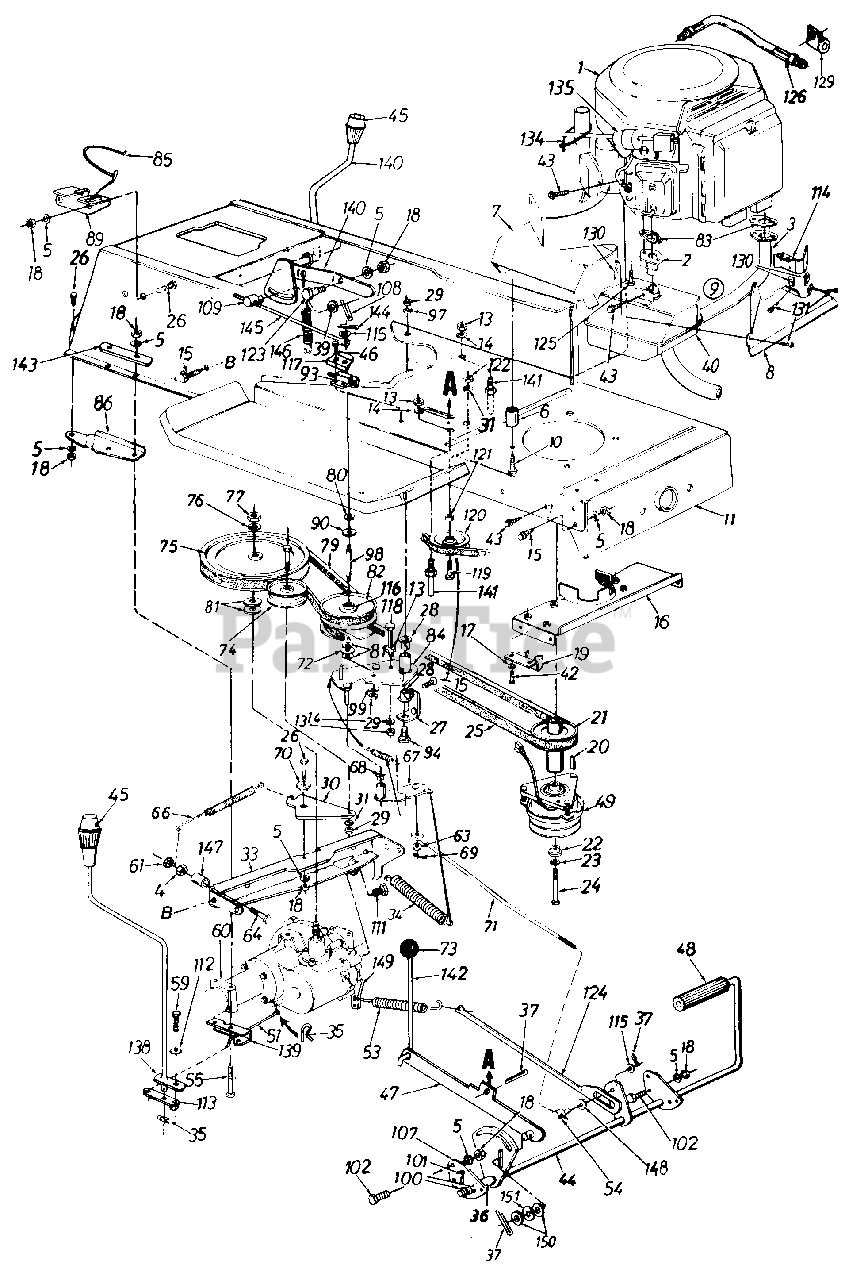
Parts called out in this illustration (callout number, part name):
1	Engine
2	Inlet Tube Ass'y.
3	Formed Tube Ass'y.
4	Hex Nut 5/16-24 Thd.
5	L-Wash. 5/16" I.D.
6	Spacer 1.25" Lg.
7	Muffler Heat Shield
8	Front Heat Shield
9	Muffler Ass'y. Comp.
10	Hex L.Wash. Tap Scr.5/16-18 x .62" Lg.
11	Lower Frame Ass'y.
13	Hex Nut 1/4"-20 Thd.*
14	L-Wash. 1/4" I.D.*
15	Hwx Wash. TT-Tap Scr. 5/16-18 x .62" Lg.
16	Belt Guard Brkt Ass'y.
17	Bell-Wash .345" I.D. x .88"
18	Hex Nut 5/16-18 Thd.
21	Engine Pulley
22	Shld. Spacer .445"I.D.
23	L-Wash.7/16" I.D.*
24	Hex Bolt 7/16-20 x 5.0" Lg.
25	Variable Speed Belt
26	Hex Bolt 5/16-18 x .75" Lg.
27	Bearing Shaft Bracket
28	Flanged Nyliner Brg. 5/8"I.D. x .88" Lg.
29	Hex Nut 3/8-24 thd.
30	Idler Bracket
31	L-Wash. 3/8" I.D.*
33	Transaxle Support Brkt
34	Ext spring .94" O.D. x 7.58"
35	Inter Cotter Pin
36	Spacer .63" I.D.
37	Cotter Pin 1/8" Dia x 1.0" Lg.
39	Fl-Wash. .51" I.D. x .75"
40	Exhaust Muffler Sub Ass'y.
42	Hex Bolt 5/16-18 x .75" Lg. (Grade5)
43	Hex Wash. Hd S-Tap Scr.1/4-20 x .50" Lg.
44	Clutch/Brake Pedal Ass'y.
45	Shift Knob
46	Hex Wash. Hd. B-Tap Scr. #10 x .5" Lg.
47	Parking Brake Lockout Brkt. Ass'y.
48	Foot Pad
49	Electric Clutch
51	Shift Lever Rod
53	Ext spring 3.6"
54	Ferrule
55	Hex Bolt 5/16-18 x 3.25"*
59	Hex Bolt 1/4-28 x .62" Lg.
60	Transaxle Complete
61	Hex L-Nut 1/4-20 Thd.
63	Fl-Wash. .34" I.D. x .68" O.D.
64	Hex Wash. TT-Tap Scr. 1/4-20 x 1 .75"
66	Ext. Spring .5" O.D. x 4.35"
68	Flanged Bearing
69	Cotter Pin 3/32" Dia.
70	Shoulder Spacer .27" Lg.
71	Speed Control Link
72	Truss Bearing .56 Dia. x 1 .25"
73	Ball Knob
74	Fl-Idler Pulley 3.25" x .75"
75	"V"-Pulley
76	Bell-Wash. .567" I.D. x 1.125"
77	Hex Jam Nut 9/16-18 Thd.
79	Variable Speed Belt
80	Snap Ring .56" Dia.
81	Fl-Wash. .56" I.D. x 1.0" O.D.
82	Variable Speed Pulley Ass'y. 5" O.D.
83	Gasket
90	Teflon Washer .565" I.D.
93	Safety Switch (Clutch)
94	Shld. Bolt 3/8-24 x 3.12" Lg.
97	Bell-Wash. .38" I.D. x .88"
98	Shaft
99	Bell-Wash. .39" I.D. x 1.12"
100	Fl-Wash. .64" I.D. x .94"
101	Cotter Pin 3/32" Dia. x 1.0"
102	Hex Wash. Hd. Scr. 5/16-18 x.62" Lg.
109	Ferrule
111	Hex Wash. Tap Scr. 5/16-18 x 1.25" Lg.
112	Bell-Wash. .265" I.D. x .75"
113	Shift Lever Link Ass'y.
114	Front Heat Shield Ext.
115	Fl-Wash. .385" I.D. x .62"
116	Needle Brgs.
117	Switch Plate
118	Hex Bolt 1/4-20 x 3.25" Lg.
119	Hex Bolt 3/8-16 x 1.25" Lg.
120	Fl-Idler w/Flanges 2.75" O.D.
121	Fl-Wash. .39" I.D. x 1.12" O.D.
122	Hex Nut 3/8-16 Thd.
123	Shld. Bolt .437" Dia. x .162"
124	Brake Rod Ass'y.
125	Hex Bolt w/Washer
126	Oil Drain
129	Clamp
130	Speed Nut #10-24 Thd.
131	Hex AB-Tap Scr. #10 x .5" Lg.
134	Cable Tie
135	Hose Clamp
138	Shift Lever Ass'y.
139	Shift Lever Support Brkt.
140	Speed Selector Lever Ass'y.
141	Belt Guard Pin
142	Brake Lockout Rod
144	Cotter Pin 1/8" x 3/4" Lg.
145	Speed Selector Rod
146	Ext. Spring 3.97" Lg.
147	Spacer .326" I.D. x .47"
148	Fl-Wash. 518" I.D. x 1.25"
149	Actuating Arm
150	Fl-Wash. .385" I.D. x .87" O.D.
151	Wave Wash. .38" I.D. x .75"
